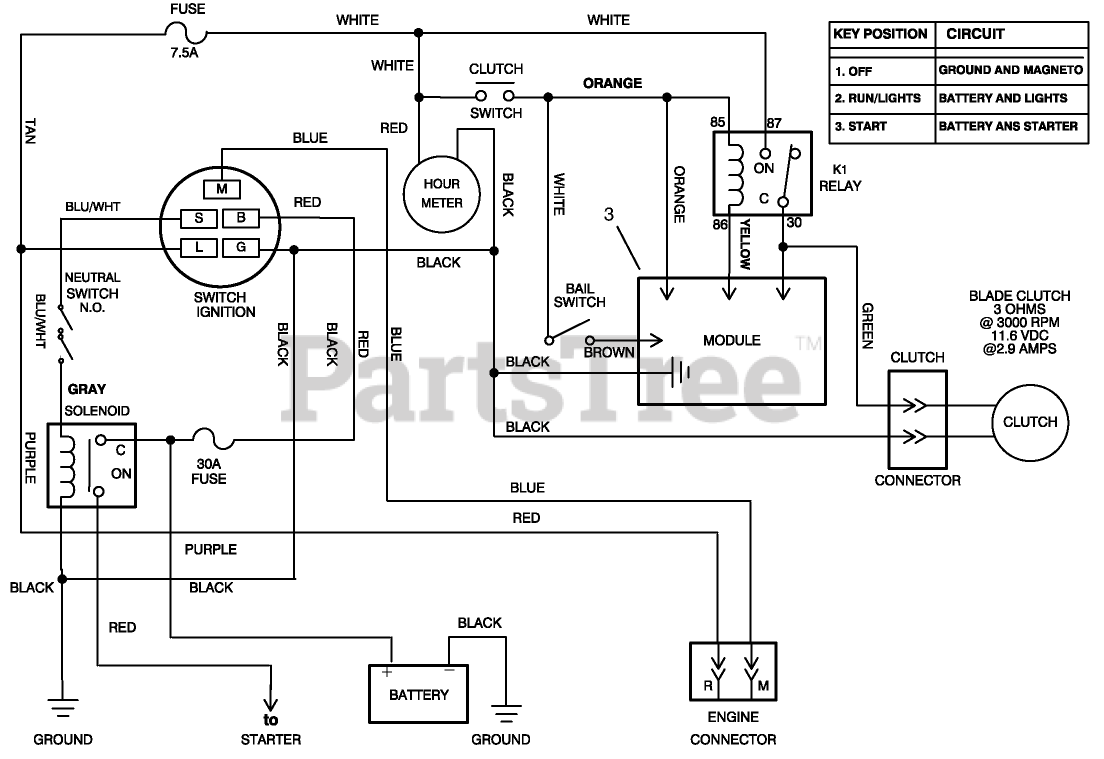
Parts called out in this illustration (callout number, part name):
1	WIRE HARNESS-18HP ELECT.
2	RELAY
3	MODULE
